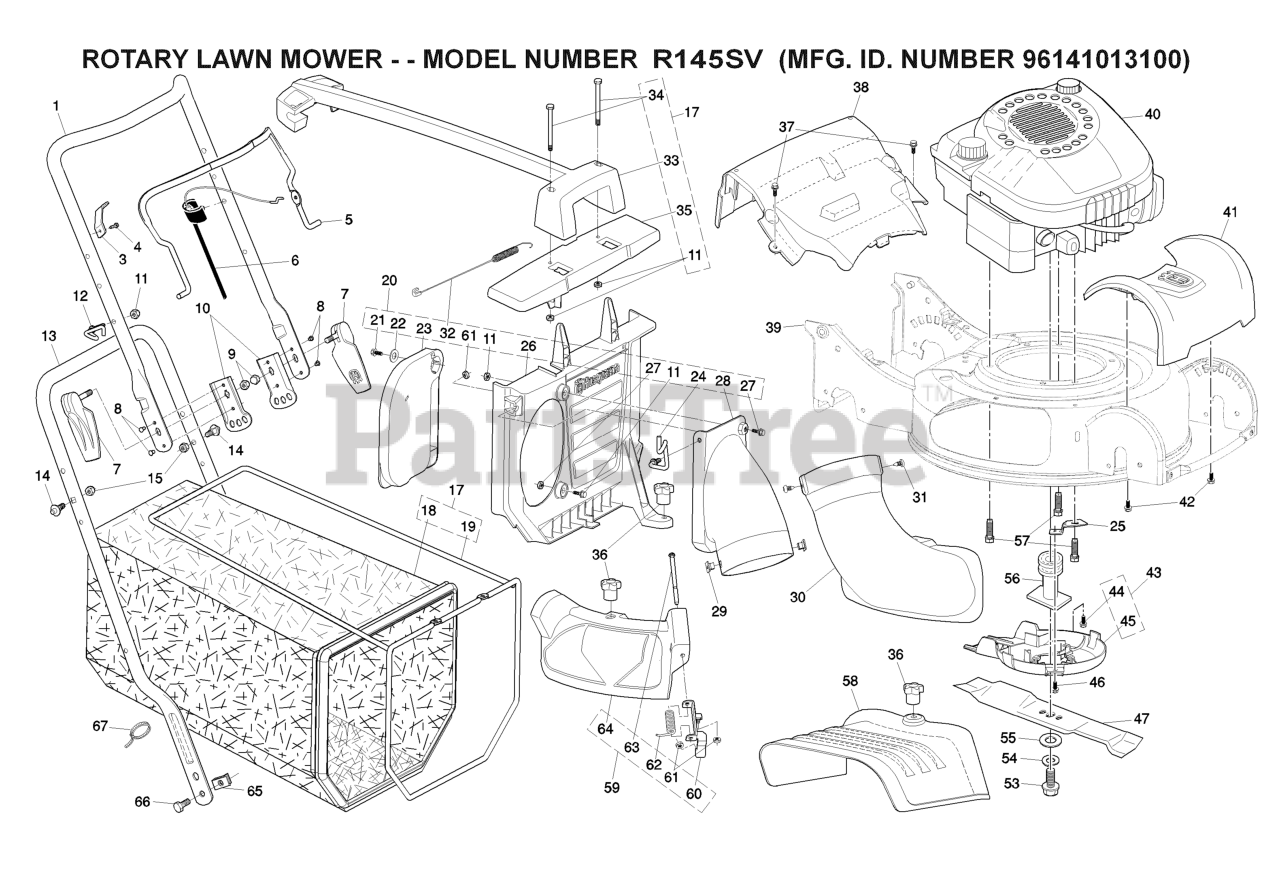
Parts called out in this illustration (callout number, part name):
1	HANDLE.ASM.UP.W/ADJ.BKT
3	BRACKET
5	BAIL CONTROL
6	CABLE.MZR.50.SNAP-IN
7	ASM.QUICK.RELEASE
9	Locknut, Hex 1/4-20
10	BRACKET.ADJ.3POS.GREY
11	NUT
12	RB GUIDE.ROPE.STD.BLK.ZIN WSL
14	STUD.QUICK.ADJUST
15	NUT.LOCK.5/16-18
22	WASHER
25	BRACKET
27	BOLT, SHOULDER
31	SCREW T-30 1/4-20 X
36	KNOB.MULCH.DOOR
37	SCREW, HEX WASHER HEAD
42	SCREW.HWH.13-16-5.8.BZP
44	HINGE SCREW
46	SCREW.HEX.WSH
47	BLADE.SWEPT.WING.45CM.H.TREAT
53	BOLT.HD.HEAD.3/8-24X2.50 (2 2)
54	LOCKWASHER
55	WASHER,HARDEN
56	ADAPTER.BLADE
57	BOLT 3/8-16X1-1/8
61	NUT.HEX.FLANGE.1/4
62	SPRING.MULCH.DOOR
63	ROD.HINGE.1/4"3.82"
64	DOOR.MULCH.GREY
67	TIE GUIDE
